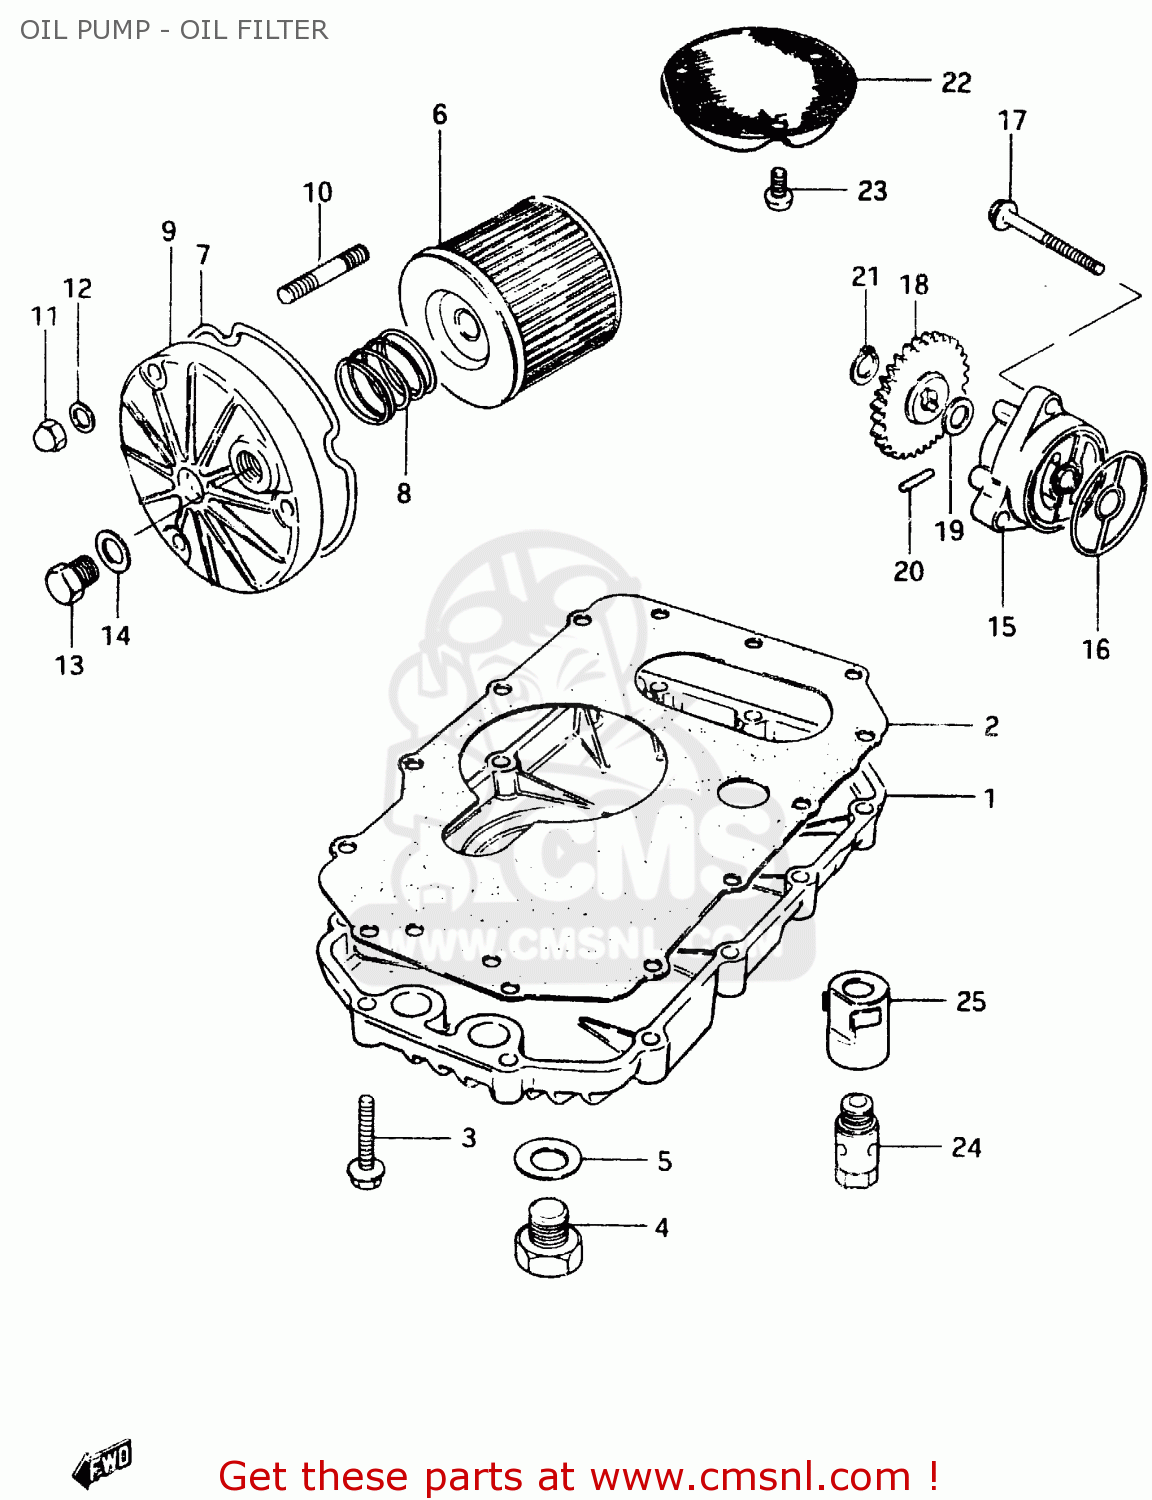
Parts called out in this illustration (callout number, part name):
1	PAN, OIL
2	GASKET,OIL PAN (MCA)
3	BOLT 6X30
4	PLUG
5	GASKET(14X19.2X2) (NAS)
6	FILTER ASSY,ENGINE OIL
7	O RING,OIL FILTER CHAMBER CAP
8	SPRING
9	CAP,OIL FILTER
10	STUD 6X20
11	NUT
12	WASHER
13	PLUG (14X12)
14	GASKET(14X19.2X2) (NAS)
15	PUMP ASSY,ENGINE OIL
16	O-RING,OIL PUMP
17	BOLT(6X32)
18	GEAR,ENG OIL PUMP DRIVEN
19	SHIM
20	PIN(4X15.8)
21	CIRCLIP
22	STRAINER,ENGINE OIL
23	SCREW 6X12
24	REGULATOR, ENGINE OIL
25	GUIDE, REGULATOR
